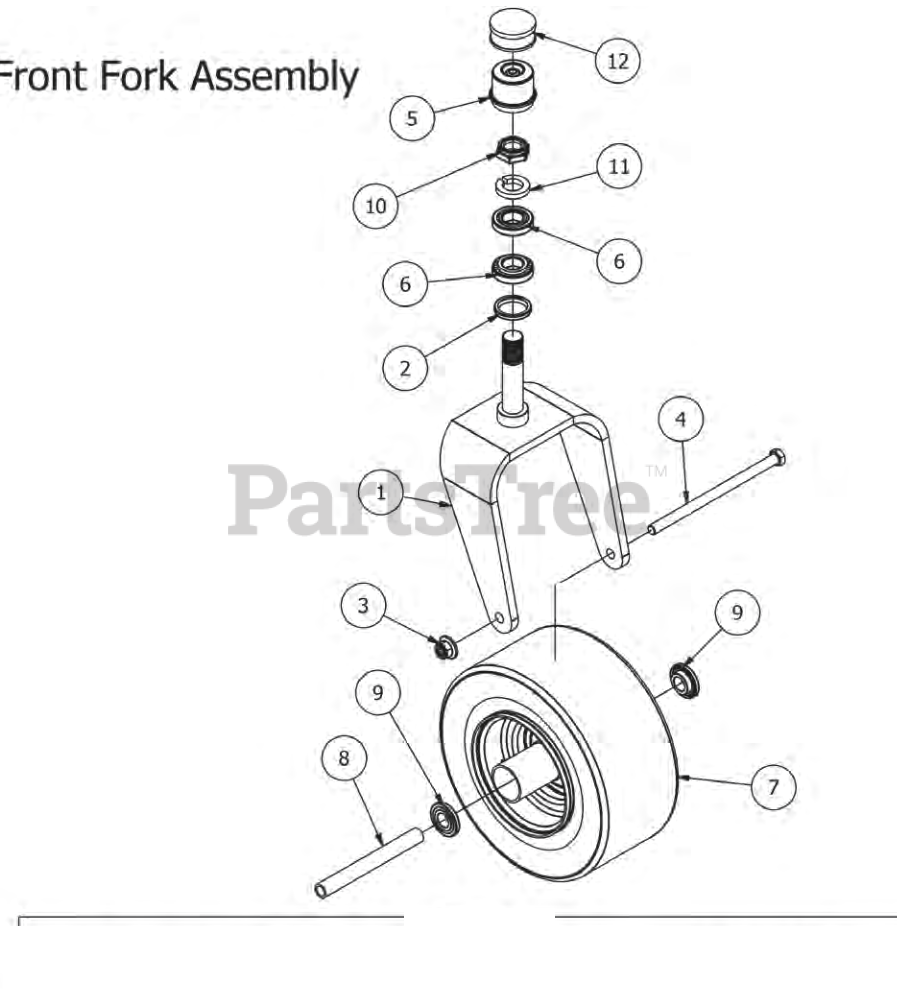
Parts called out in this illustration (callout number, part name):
1	Front Fork
3	1/2-13 Nylon Flange Nut-Orange
4	1/2" x 9" Bolt
5	Dust Cover
7	Tire and wheel assembly
8	Front Wheel Spanner
9	Wheel Bearing
10	1" Fine Thread 1/2 Nut
11	1" Lock Washer
12	Spring Cap Cover
